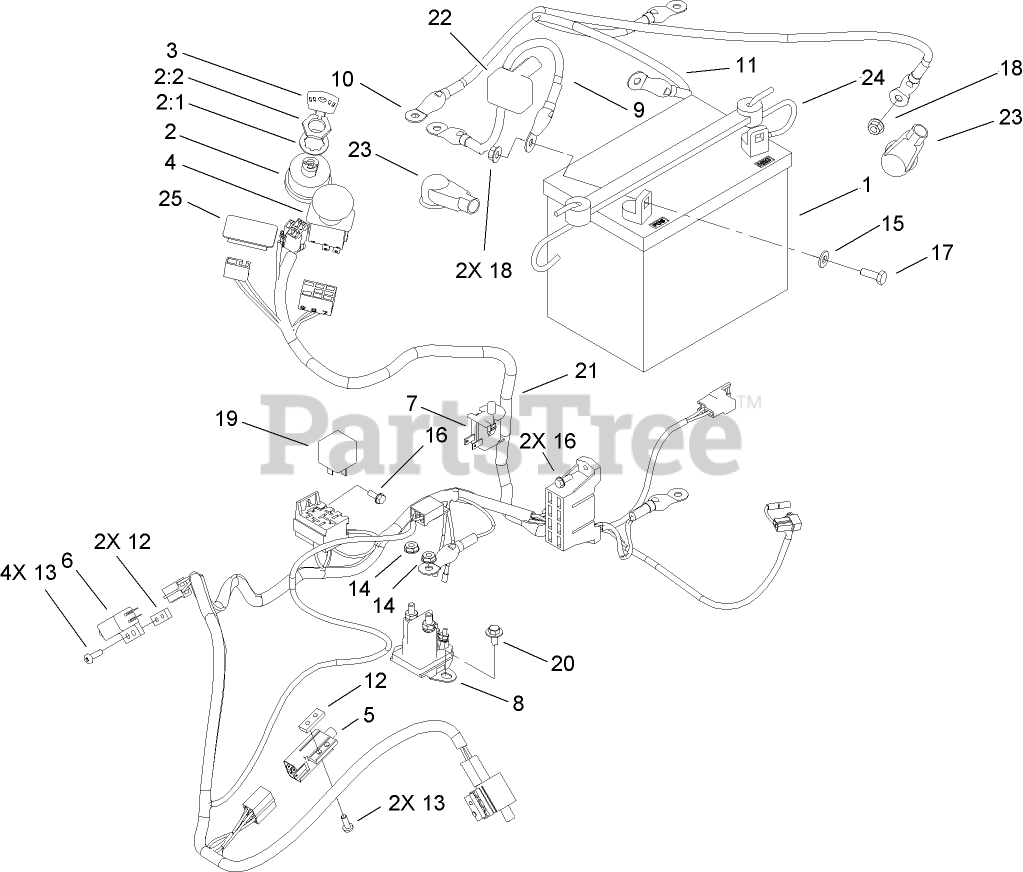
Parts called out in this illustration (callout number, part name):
2:1	WASHER-LOCK
2:2	NUT-HH
3	KEY-IGNITION
4	SWITCH-PTO,ON-ON-NONE
7	SWITCH-BAIL
8	SOLENOID-STARTER
9	WIRE ASM
10	WIRE ASM
11	CABLE
12	PLATE-TAPPED
13	SCREW-PPHTF
14	NUT-KEPS
15	WASHER-FLAT
16	SCREW-TAPTITE
17	SCREW-HH
18	NUT-HF
19	RELAY
20	SCREW-HHFTF
21	HARNESS-WIRE
22	BOOT-TERMINAL
23	BOOT-INSULATOR, TERMINAL
24	HOLDDOWN-BATTERY
25	PLUG-HOLE
